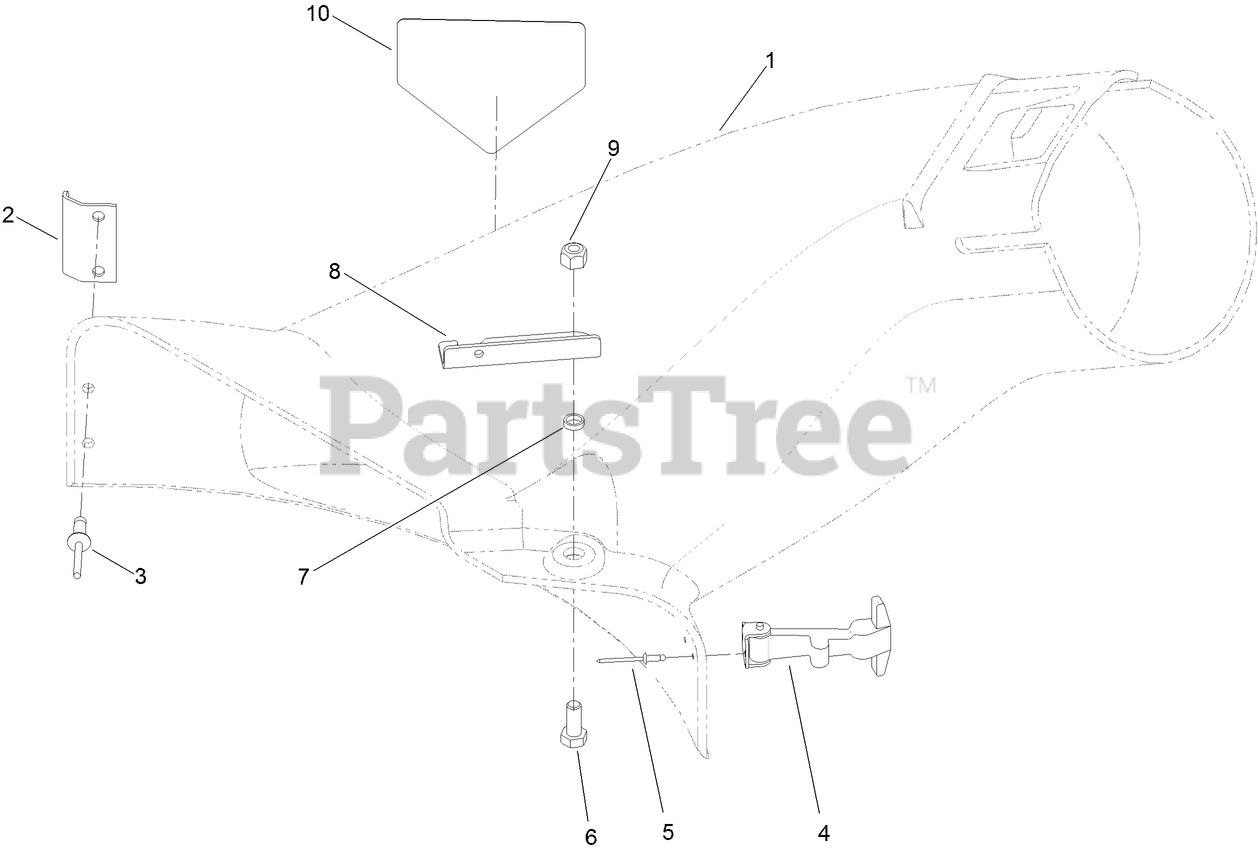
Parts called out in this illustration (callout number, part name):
1	ELBOW-BAGGER
2	BRACKET-ELBOW
3	RIVET-BLIND
4	HANDLE ASM
5	RIVET-POP
6	SCREW-HH
7	BUSHING
9	NUT-LOCK, NI
10	DECAL-DANGER, CE
